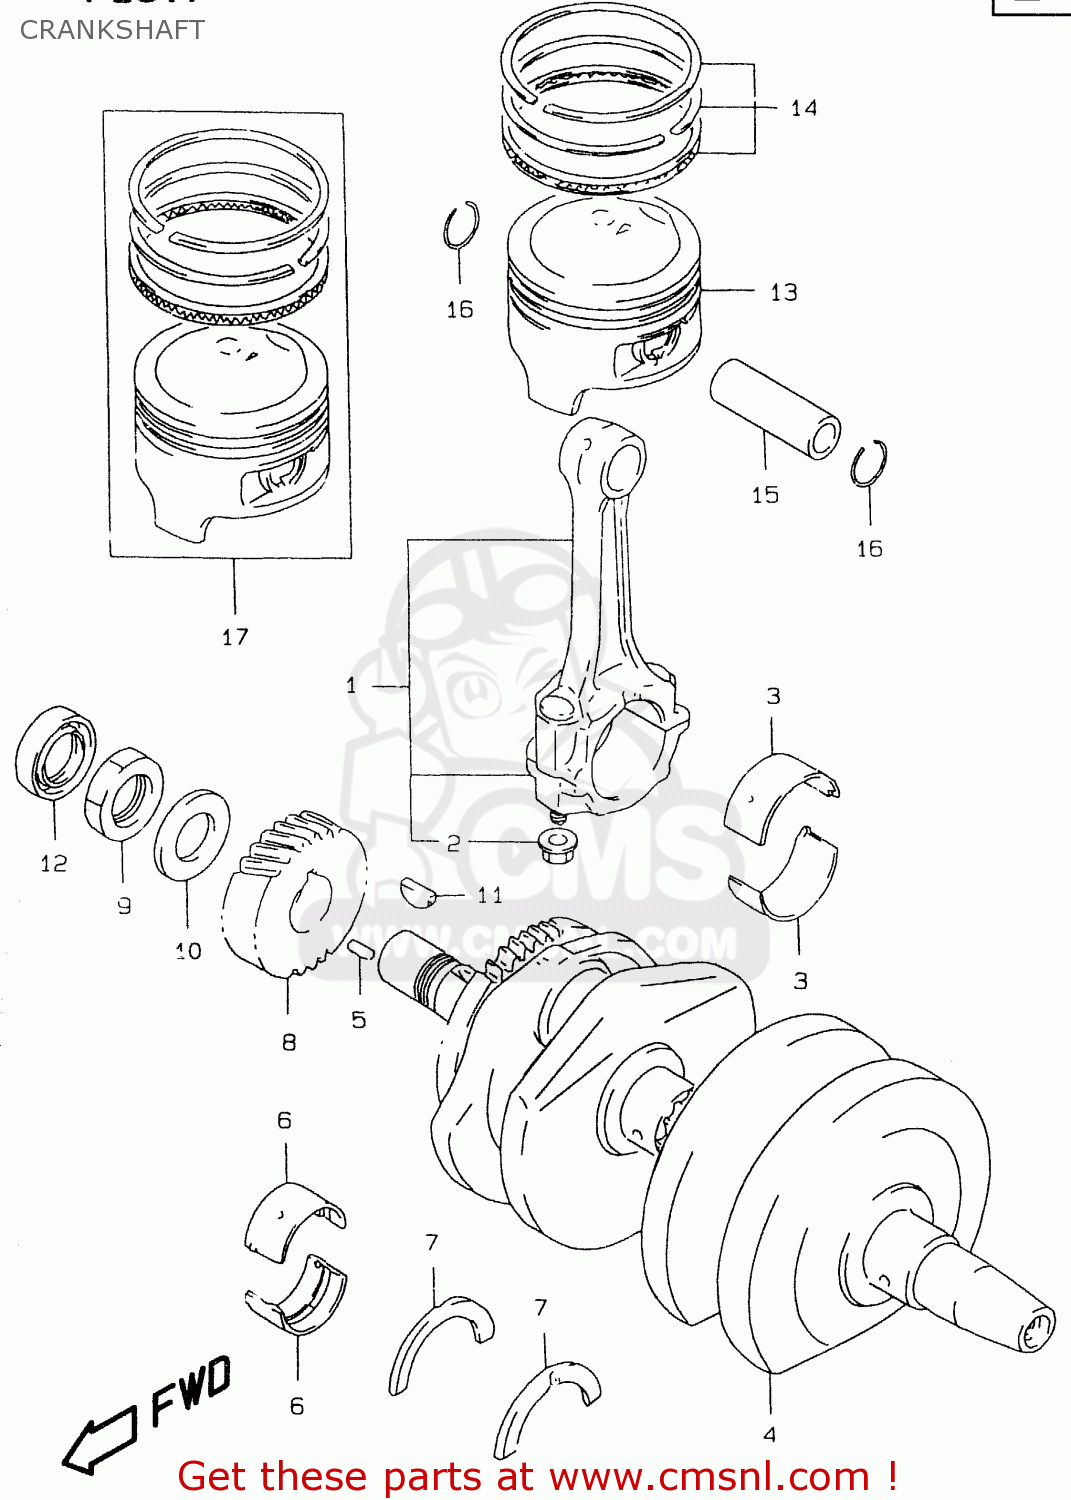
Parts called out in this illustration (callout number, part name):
1	ROD ASSEMBLY,CONNECTING
2	NUT
3	BEARING,CRANK PIN
4	CRANKSHAFT
5	PIN
6	BEARING,CRANKSHAFT(GREEN)
7	BEARING,CRANK THRUST
8	GEAR,PRIMARY DRIVE NO.28
9	NUT
10	WASHER
11	KEY
12	SEAL,OIL(22X40X8)
13	PISTON (74.00MM)
14	RING SET,PISTON
15	PIN,PISTON (18MM)
16	CIRCLIP,PISTON PIN
17	PISTON SET(OS:0.5)
